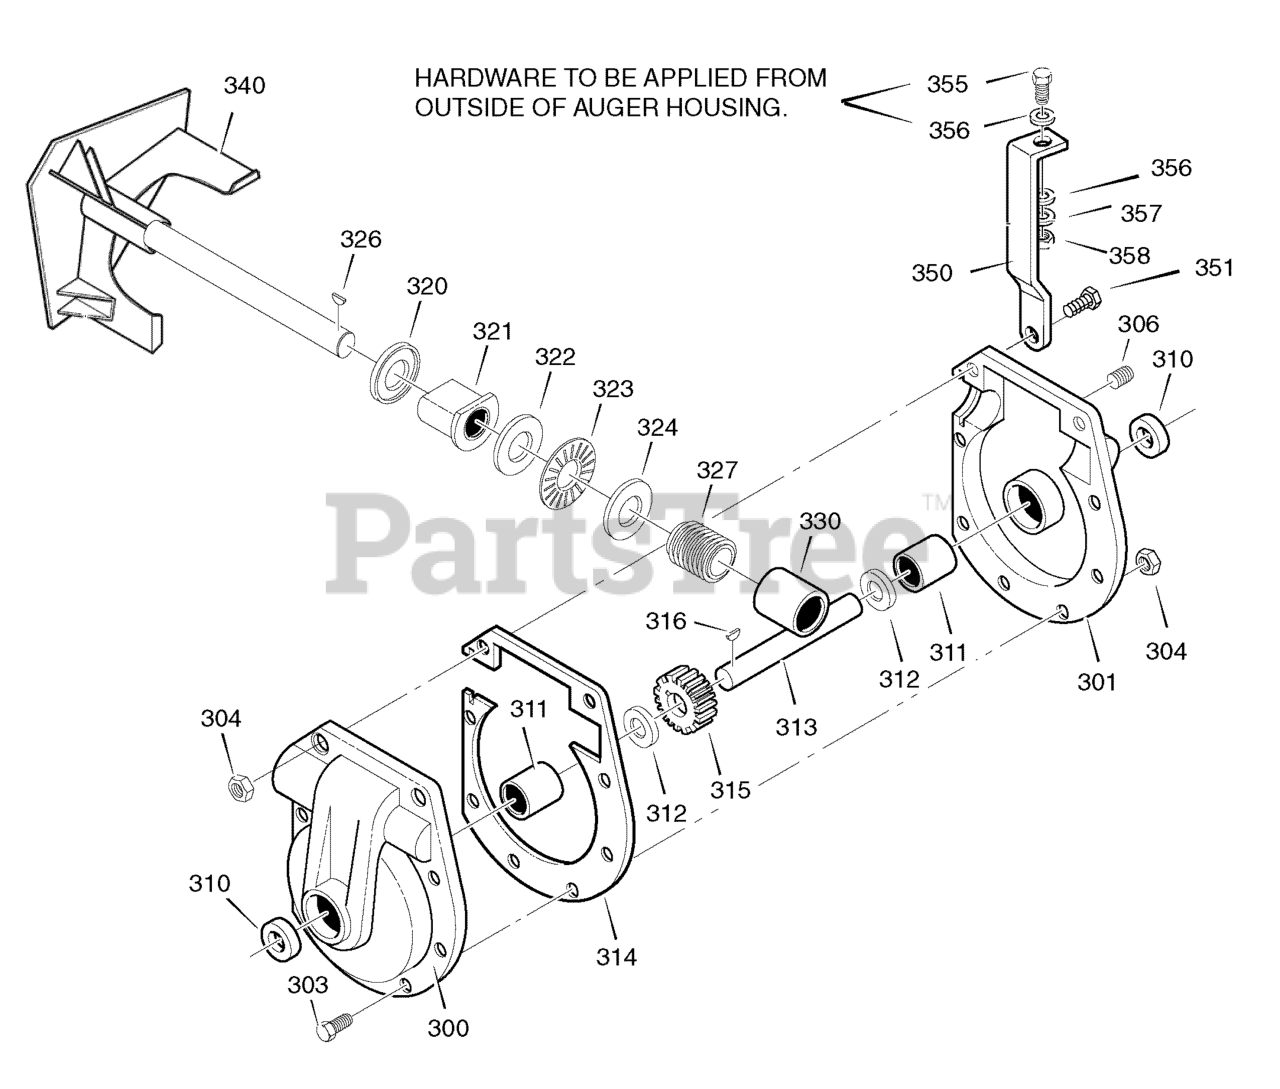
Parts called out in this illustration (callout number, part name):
300	CASE, GEAR, RH
301	CASE, GEAR, LH
303	SCREW, 5/16-24 X 1.00
304	NUT, 5/16-24
306	PLUG, PIPE 0.25-18
310	SEAL, OIL
311	BEARING, SLEEVE
312	WASHER, FLAT
313	SHAFT, AUGER OUTPUT
314	GASKET, GEAR BOX
315	WORM GEAR
316	KEY, WOODRUFF #91
320	RING, QUAD 0.924 ID
321	BEARING, FLANGE
322	WASHER, FLAT
323	BEARING, ROLLER
324	WASHER, FLAT
326	KEY, Woodruff
330	BEARING, SLEEVE
350	BRACE, GEAR BOX
351	SCREW 5/16-24 X 1.75
355	SCREW 5/16-18 X 1.25
356	WASHER, FLAT
357	WASHER, SPTLK
358	NUT, REGHEX 5/16-18
